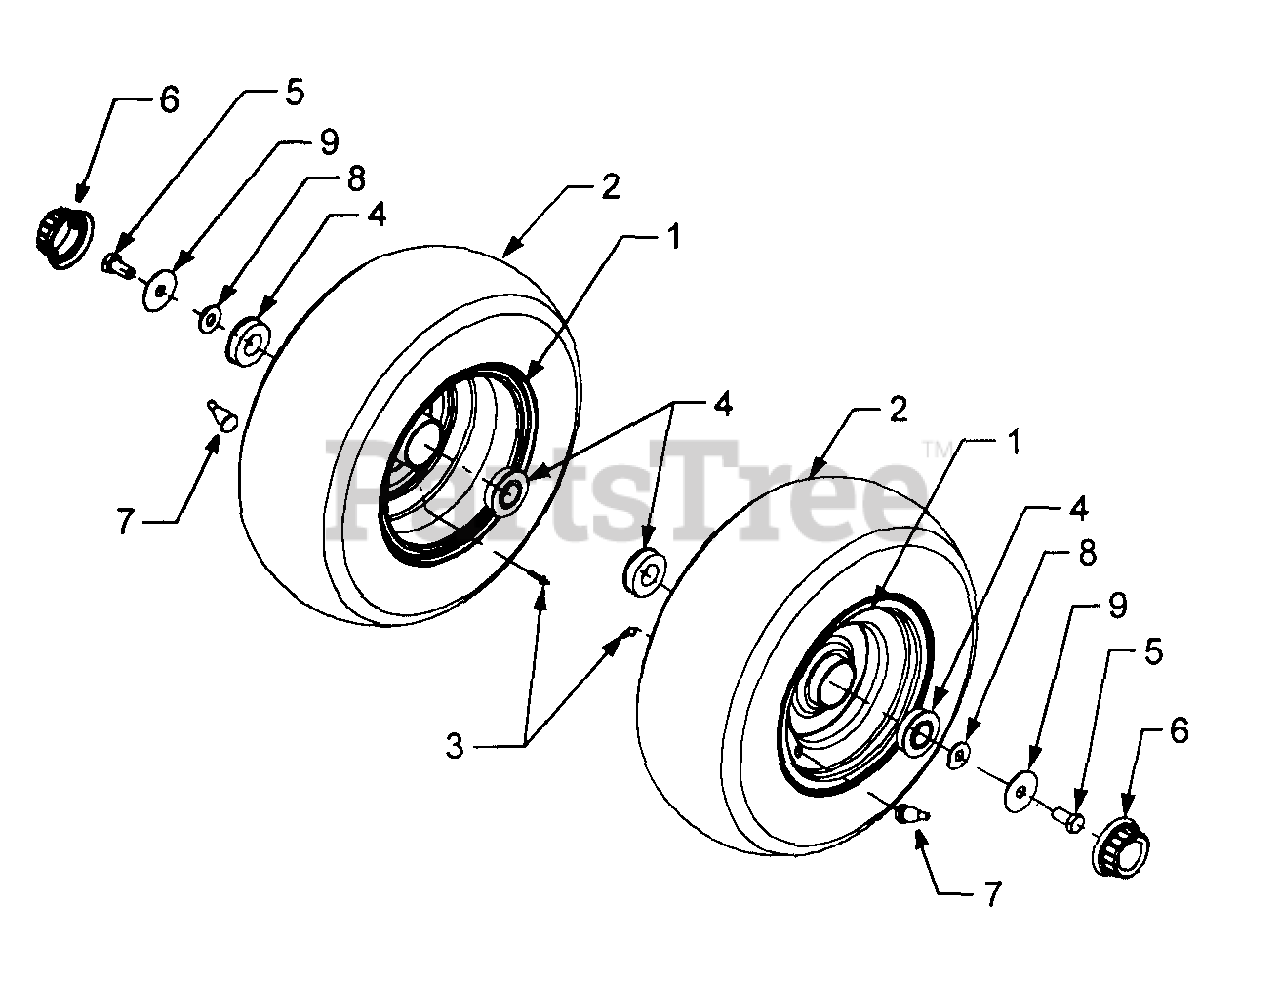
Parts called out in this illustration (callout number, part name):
1	Rim Assembly, Wheel
2	Tire, Turf, 16 x 7.5 x 8.0
3	Lube Fitting
4	Bearing, Ball
5	Screw, Hex Cap, 1/2-13 x 1.0 GR5
6	Hubcap
7	Valve, Tubeless Air
8	Washer, Flat, .531 x 1.25 x .1
9	Washer, Flat, .535 x 1.92 x .060
